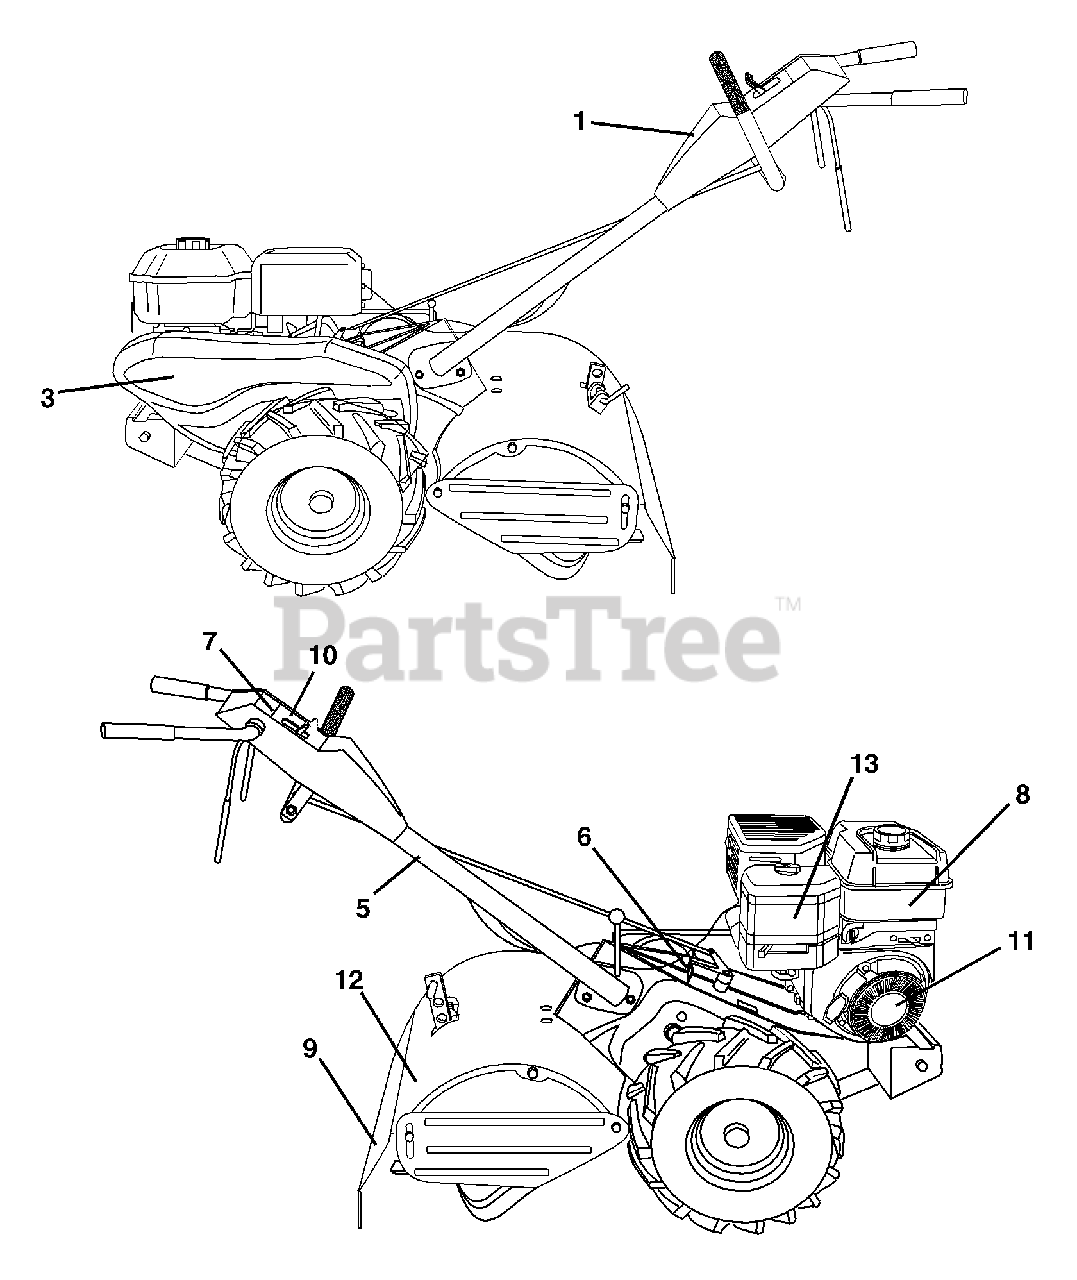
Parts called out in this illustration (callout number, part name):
1	Decal, Logo
3	Decal, Logo
5	Decal, Hand Placement
6	Decal, Shift Indicator
7	Decal, Control Panel
8	Decal, OHV.N-I/C
9	Decal, Warning, Rotating Tines
10	Decal, Logo
11	Decal, Rewing Intek
12	Decal, Warning Till
13	Decal, B&S Tiller
